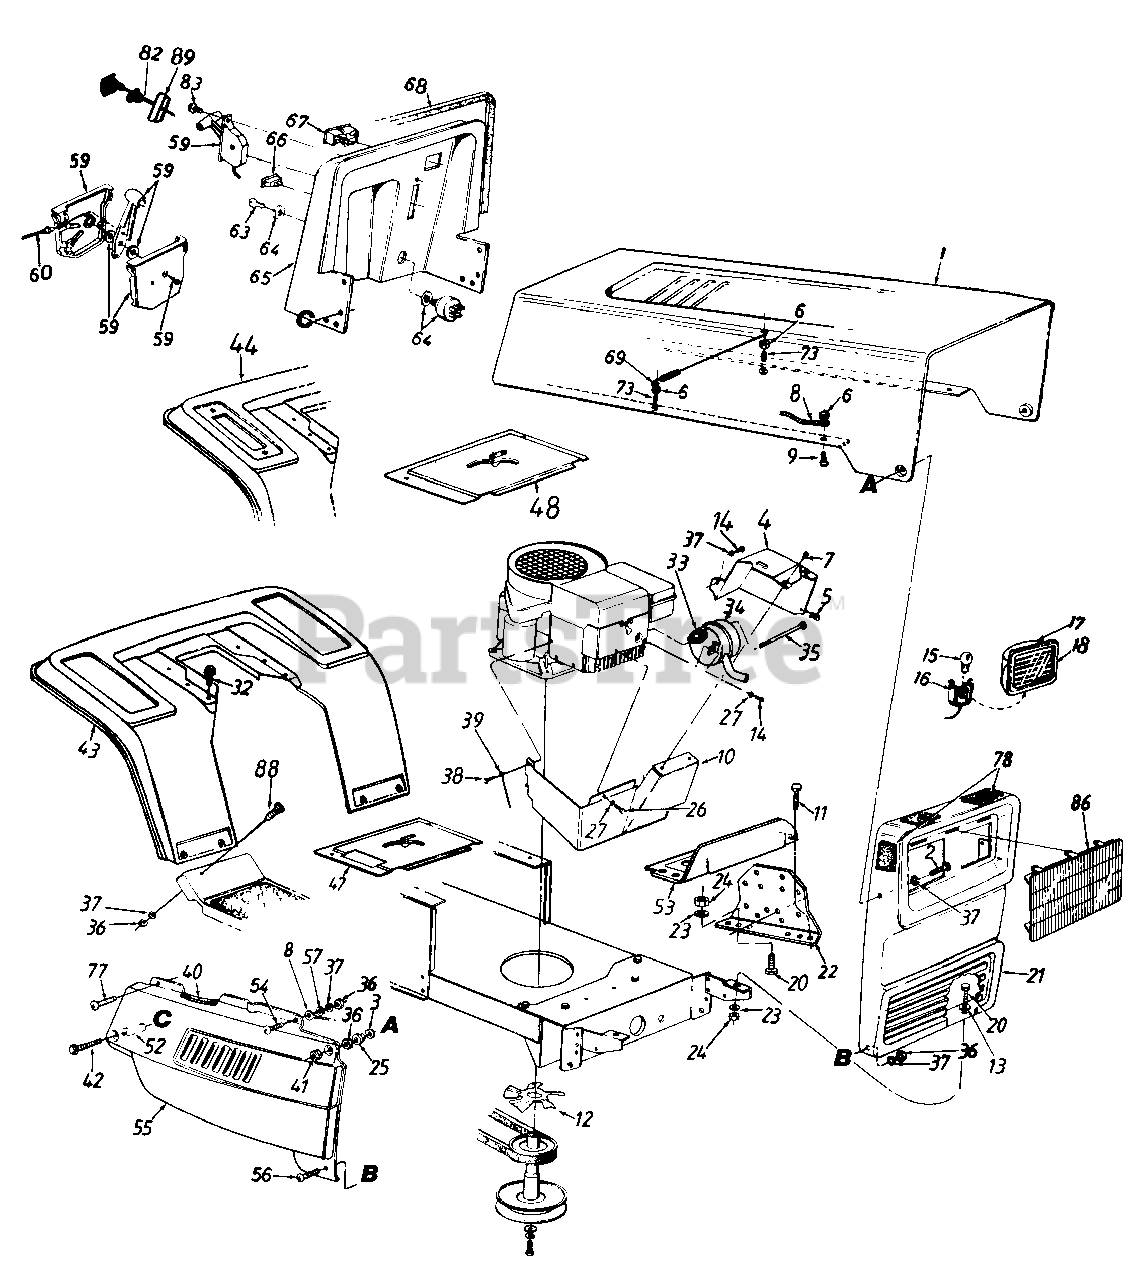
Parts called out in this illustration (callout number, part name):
1	Hood
2	Hex Bolt 1/4-20 x .88" Lg.
3	Washer .39" I.D. x .62"
4	Muffler Heat Shield - L.H.
5	Speed Nut #10-24 Thd.
6	Hex Sems Nut #10-24 Thd.
7	Hex B-Tap Scr. #10 x .38" Lg.
8	Hood Stop
9	Truss Hd. Scr. #10-24 x 1/2"
10	Muffler Heat Shield - Front
11	Hex Wash. Hd. B-Tap Scr. 5/16-18 x .5" Lg.
13	Fl-Wash. .344" I.D. x 1" O.D.
14	Hex Tap Scr. 1/4-20 x .5" Lg.
15	Bulb
16	Twist Lock - Bulb Socket
17	Headlight Housing
18	Lens
20	Hex Bolt 5/16-18 x .75" Lg.
24	Hex Nut 5/16-18 Thd.
25	Shld. Spacer
27	Spr. Wash. 1/4" I.D.
33	Exhaust Gasket
34	Muffler (B & S)
35	Shoulder Bolt
36	Hex Nut 1/4-20 Thd.
37	L-Wash. 1/4" I.D.
38	Truss Mach. Scr. 5/16-18 x .75" Lg.
39	Ground Wire 7.5"
40	Trim Strip - 12"
41	Acorn Nut 1/4-20 Thd.
42	Hex TT-Tap Scr. 1/4-20 x 1.75" Lg.
52	Spacer 1.32" Lg.
57	Fl-Wash..281" I.D. x .73" O.D.
59	Throttle Control Box Ass'y.
60	Throttle Control Wire (B & S)
63	Ignition Key
64	Ignition Switch
67	Ammeter
68	Trim Strip - 31"
69	Hood Spring
73	Hex Scr. #10-24 x 1.0" Lg.
77	Hex Wash. Hd. Tap Scr. 1/4 x .75" Lg.
78	Foam Strip 3/8 x 1-1/8" x 1-1/2" Lg.
82	Choke Control 29" Lg.
83	Truss Mach. AB-Tap Scr. #10 x .5" Lg.
86	Headlight Bezel
88	Truss Mach. Scr. 1/4-20 x .5" Lg.
89	Retainer Clip
